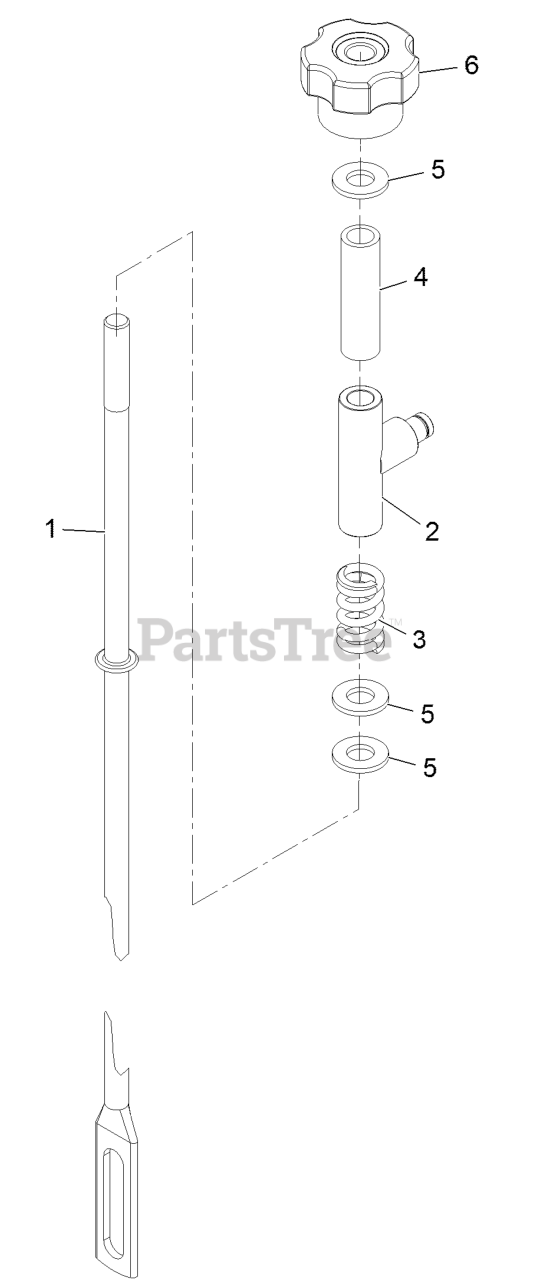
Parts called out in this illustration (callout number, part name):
1	ROD, RIGHT
3	SPRING, COMPRESSION
5	WASHER-FLAT
